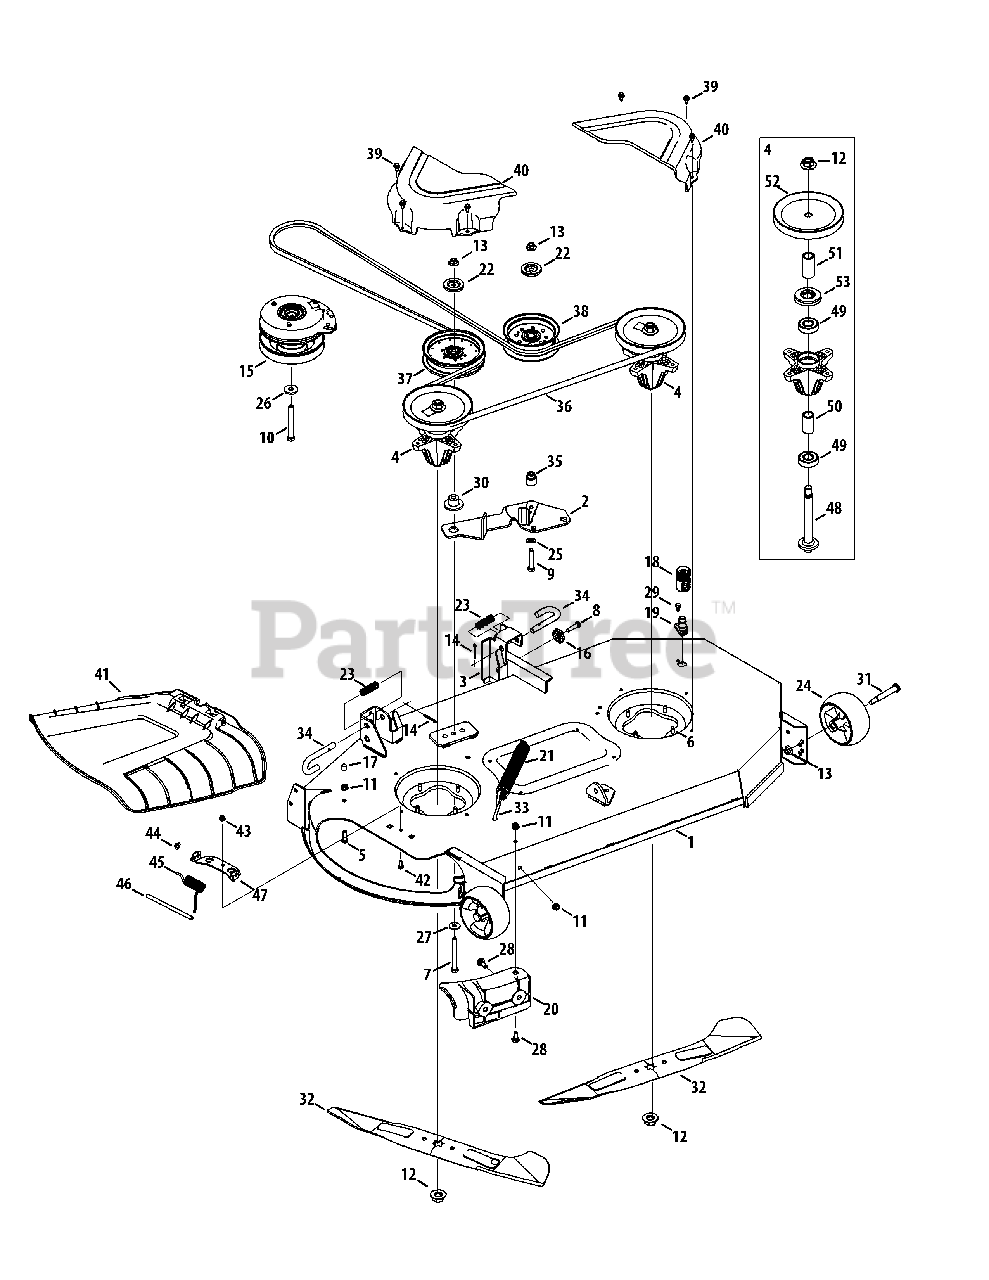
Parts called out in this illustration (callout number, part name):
1	46" Deck
2	Deck Idler Assembly
3	Deck Lift Bracket
4	Spindle Assembly
5	Hex Cap Screw, 5/16-18 x 1.00
6	Hex Washer Screw, 5/16-18 x .750
7	Hex Cap Screw, 3/8-16 x 3.50
8	Hex Cap Screw, 3/8-16 x 1.50
9	Hex Cap Screw, 3/8-16 x 2.00
10	Screw, 7/16-20 x 3.25
11	Flange Lock Nut, 5/16-18
12	Hex Flange Nut, 5/8-18
13	Flange Lock Nut, 3/8-16
14	Cotter Pin, 5/32 x 1.25
15	Electric PTO Clutch
16	Deck Adjustment Gear
17	Cap, .290 x .500
18	Water Nozzle Adapter
19	Deck Wash Nozzle
20	Baffle, Discharge
21	Extension Spring, 1.25 OD x 1.751
22	Pulley Cap
23	Compression Spring, .66 x 1.9
24	Deck Ball Wheel, 5.0
25	Flat Washer, .406 x .875 x .059
26	Flat Washer, .450 x 1.25 x .164
27	Flat Washer, .406 x 1.00 x .105
28	Shoulder Screw, .428 x .160, 5/16-18
29	Shoulder Screw, 1/4-20 x 0.50
30	Shoulder Spacer
31	Shoulder Screw, .5 x 2.5 x 3/8-16
32	Blade, 2 in 1, 23.25
33	Deck Spring Rod
34	Deck Hanger Rod
35	Shoulder Spacer
37	Idler Pulley, 5.00 Dia.
38	Pulley, Idler, 4.50" Dia.
39	Hex Washer Screw, 1/4-20 x .625
40	Belt Cover
41	Chute Deflector Assembly
42	Hex Cap Screw, 1/4-20 x .62
43	Nut, Flange Lock, 1/4-20, Nylon
44	Push Cap
45	Spring, Torsion, .440 ID x 1.75
48	Spindle Shaft
49	Ball Bearing
50	Spacer, .792 x 1.060 x 1.860
51	Spacer, .8 x 1.1 x 2.26
52	Deck Pulley
53	Bearing Shield
